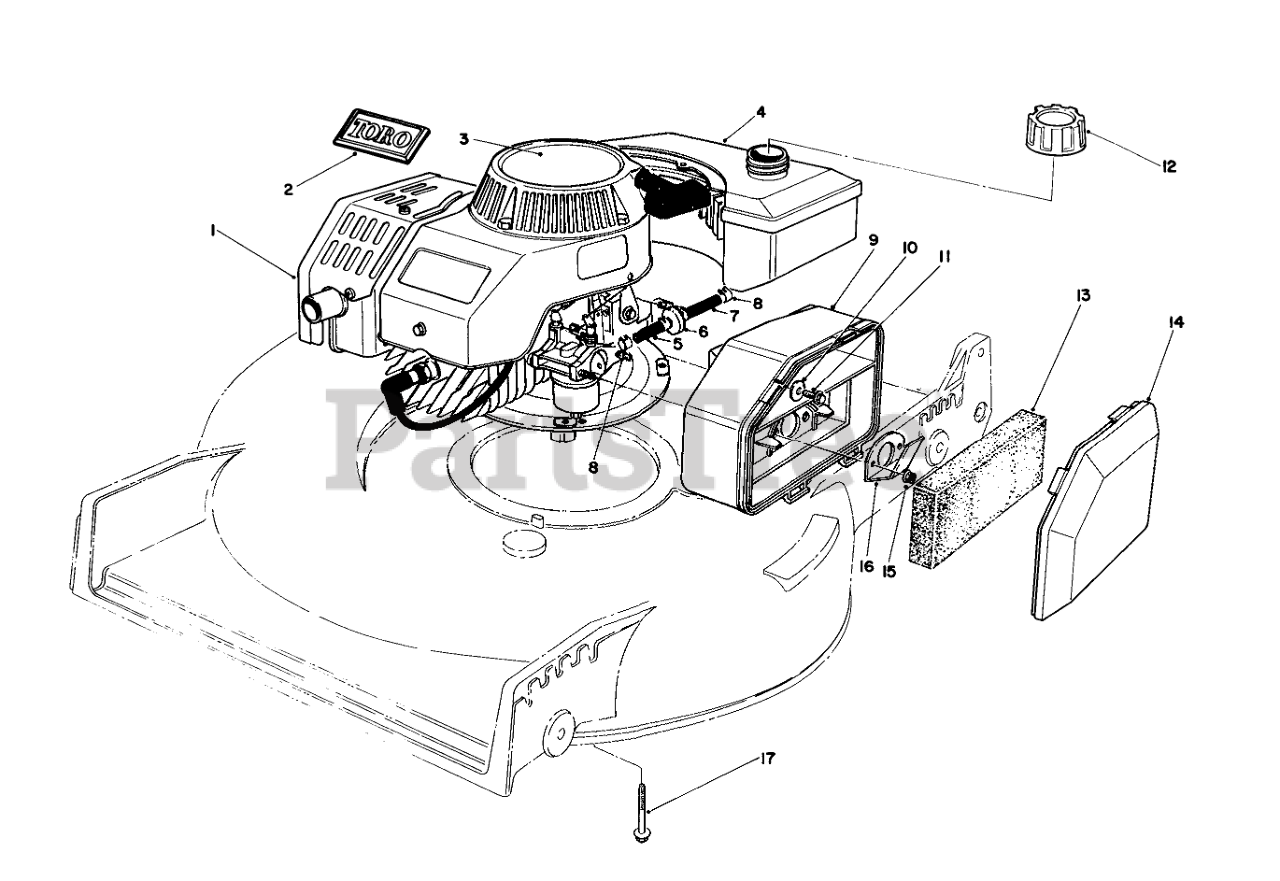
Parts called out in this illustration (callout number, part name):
2	TORO LOGO PLT
3	DECAL
4	Gas Tank Assembly
5	HOSE-FUEL
6	FILTER-FUEL
7	HOSE-FUEL
8	CLAMP-FUEL LINE
9	AIR CLEANER
10	WASHER-FLAT
11	SCREW-HH
12	GAS CAP ASM
13	FILTER
14	AIR CLEANER COVER
15	NUT-LOCK
16	SPIT BACK DEFLECTOR
17	SCREW-HHF
